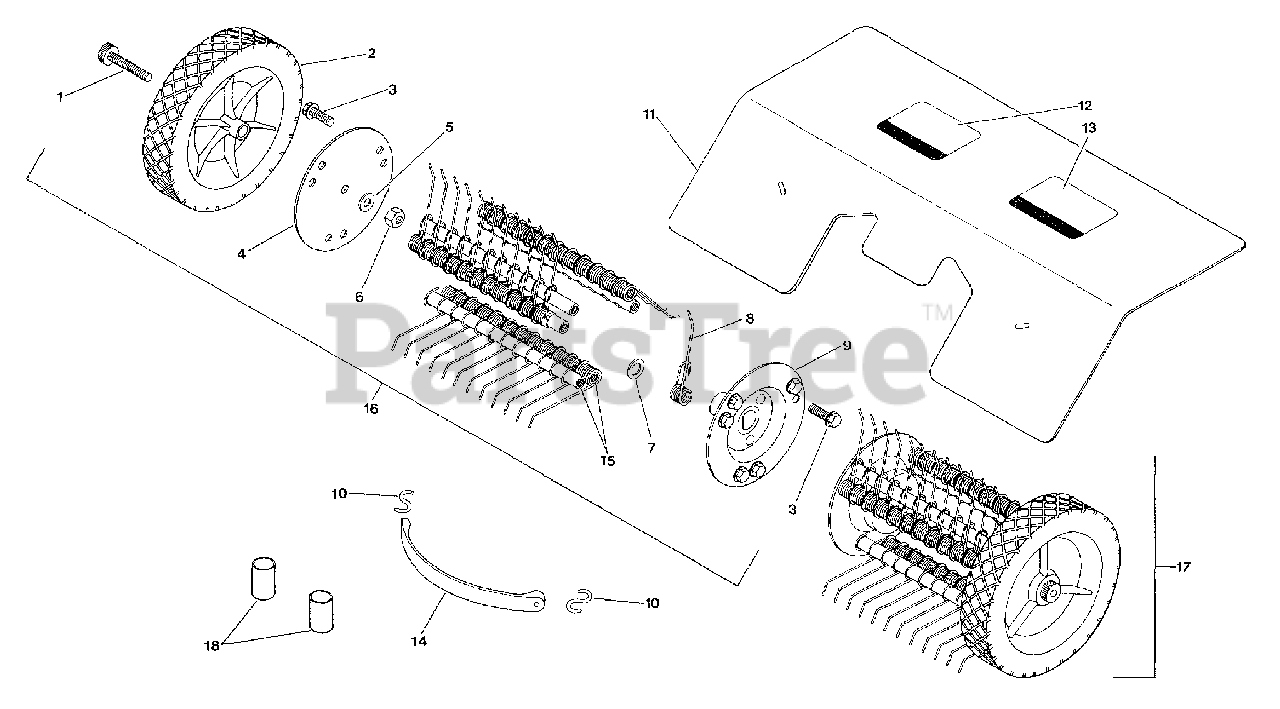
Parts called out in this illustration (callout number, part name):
1	Bolt, Socket Hd., 3/8-16 x 1-1/2
2	Wheel/Tire Assembly
3	Whiz Bolt, 5/16-18 x 3/4
4	End Cap - outer
5	Lockwasher, 3/8
6	Hex Nut, 3/8-16
7	Washer, Flat, 1/2
8	Spring Tine Kit
9	End Cap - inner
11	Debris Shield
12	Decal - Caution
13	Decal - Warning
14	Strap, Debris Shield
15	Bar, tine retaining/tine attachment
16	Rake Assembly - Right
17	Rake Assembly - Left
